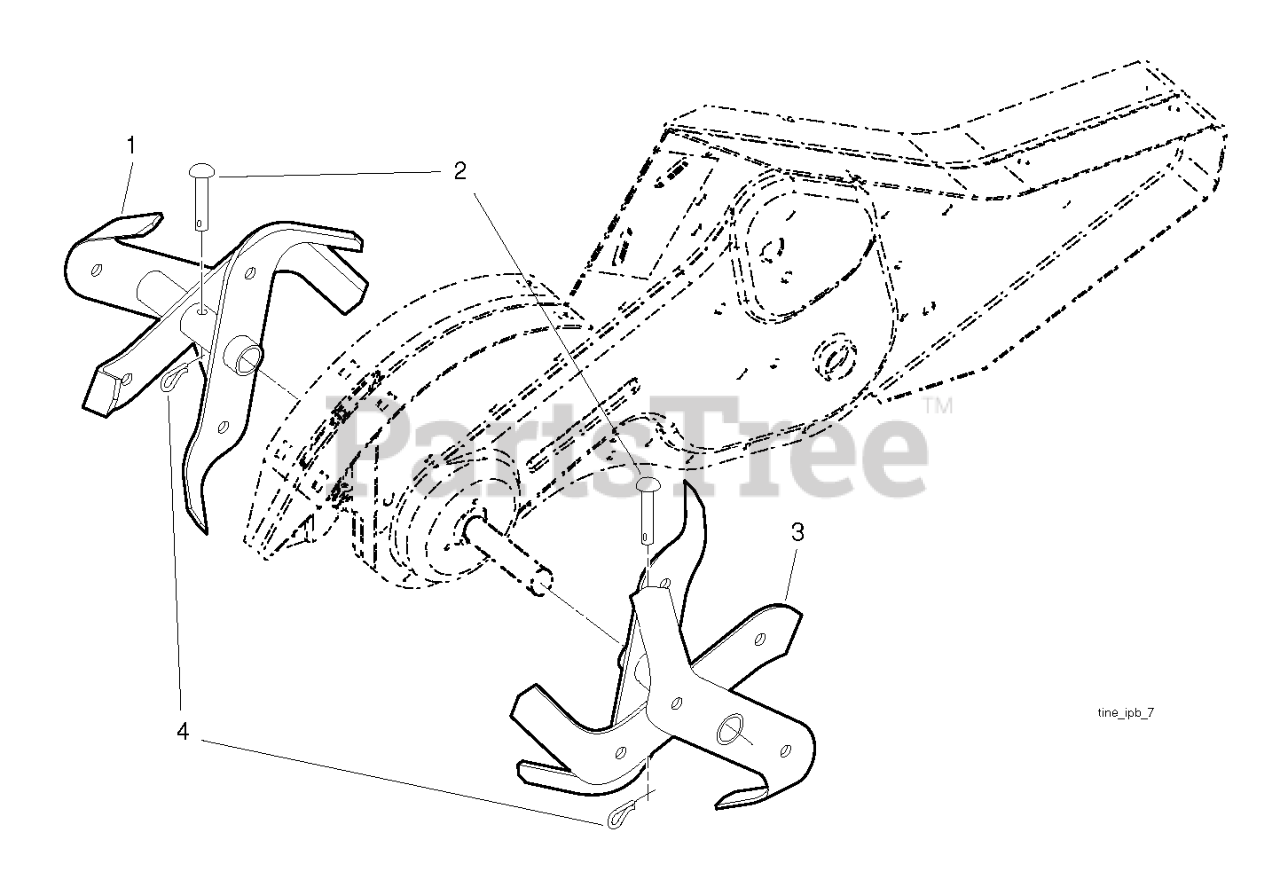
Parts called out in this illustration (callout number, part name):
1	TINE.ASM.LH.TILLER.BLACK
2	PIN RETAINING SCREW
3	TINE.ASM.RH.PNT.479
4	SPRING RETAINER
